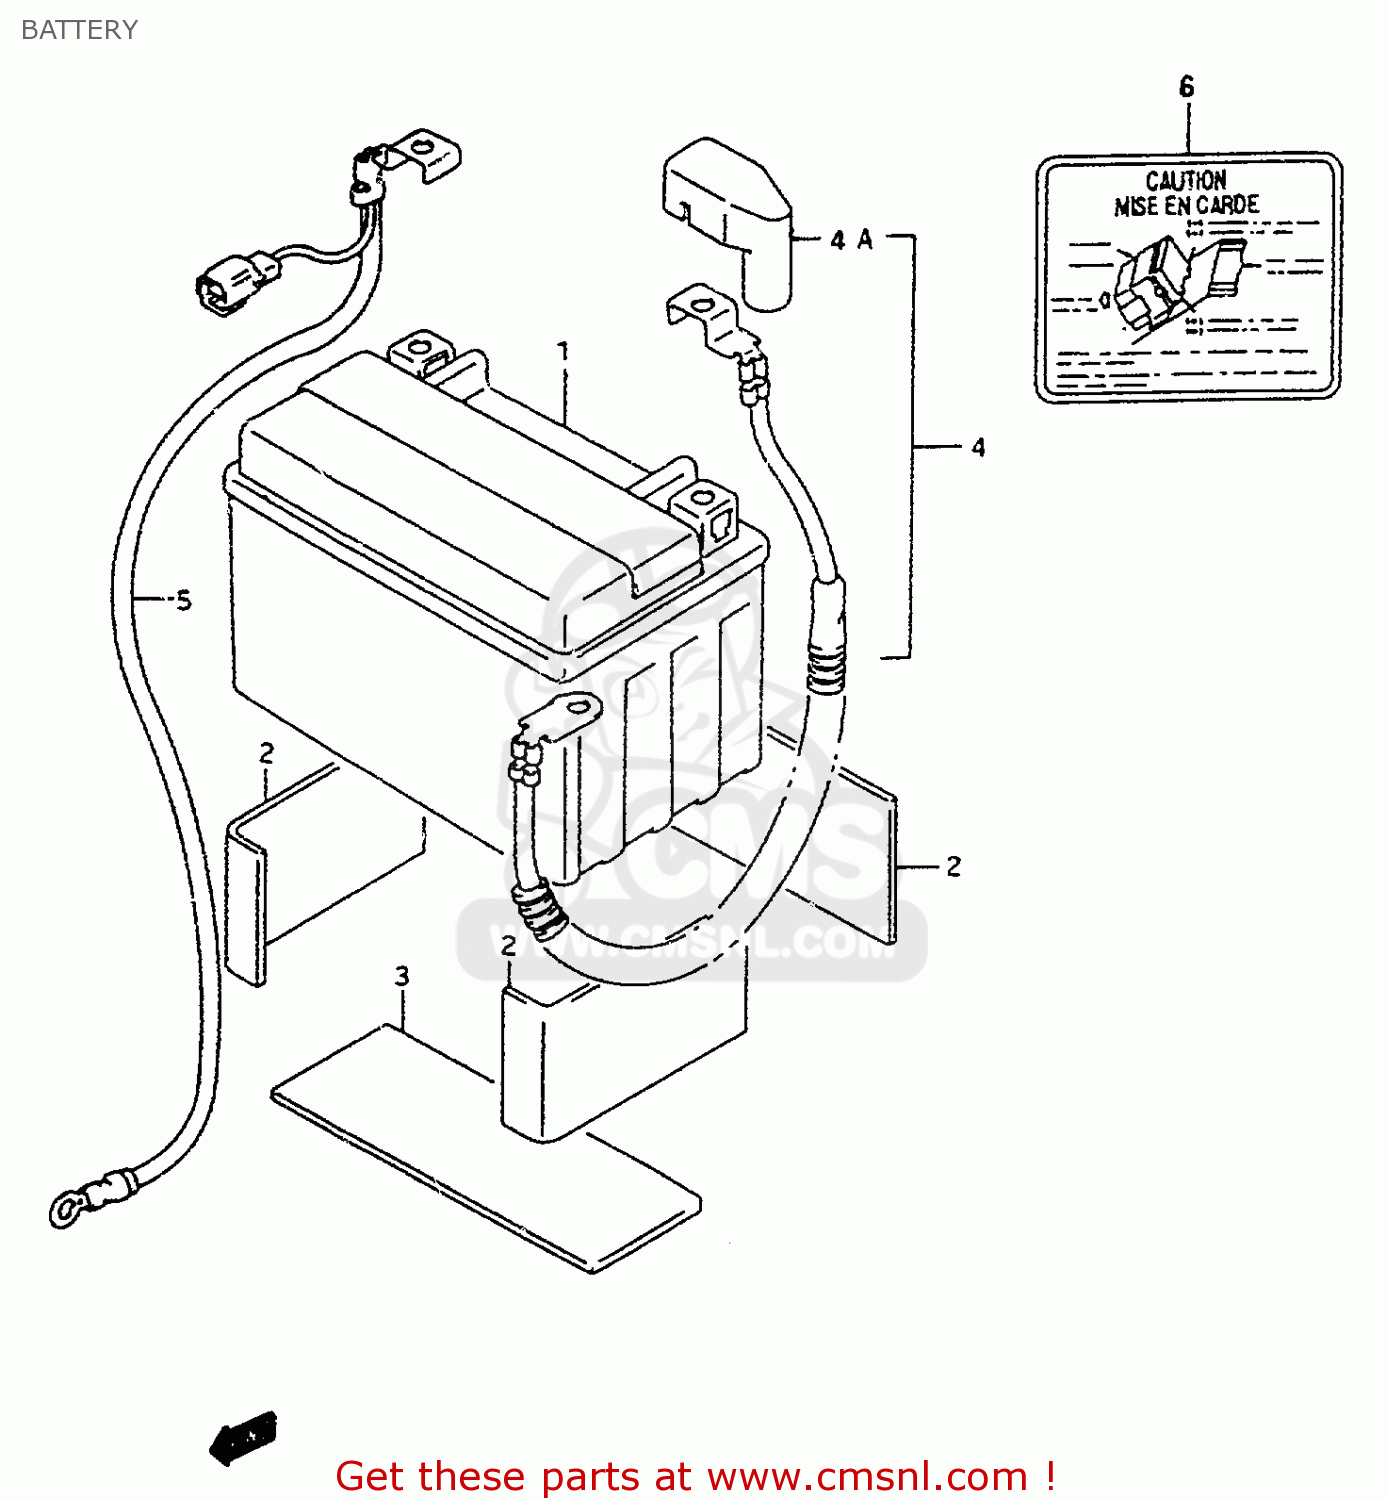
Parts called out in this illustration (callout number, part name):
1	BATTERY ASSY(YTX9-BS,12V8AH)
2	PROTECTOR(170X95X3.0)
3	PROTECTOR(170X95X3.0)
4	WIRE,BATTERY PLUS LEAD
4A	CAP,BATTERY PLUS
5	WIRE,BATTERY MINUS
6	PLATE,BATTERY CAUTION
